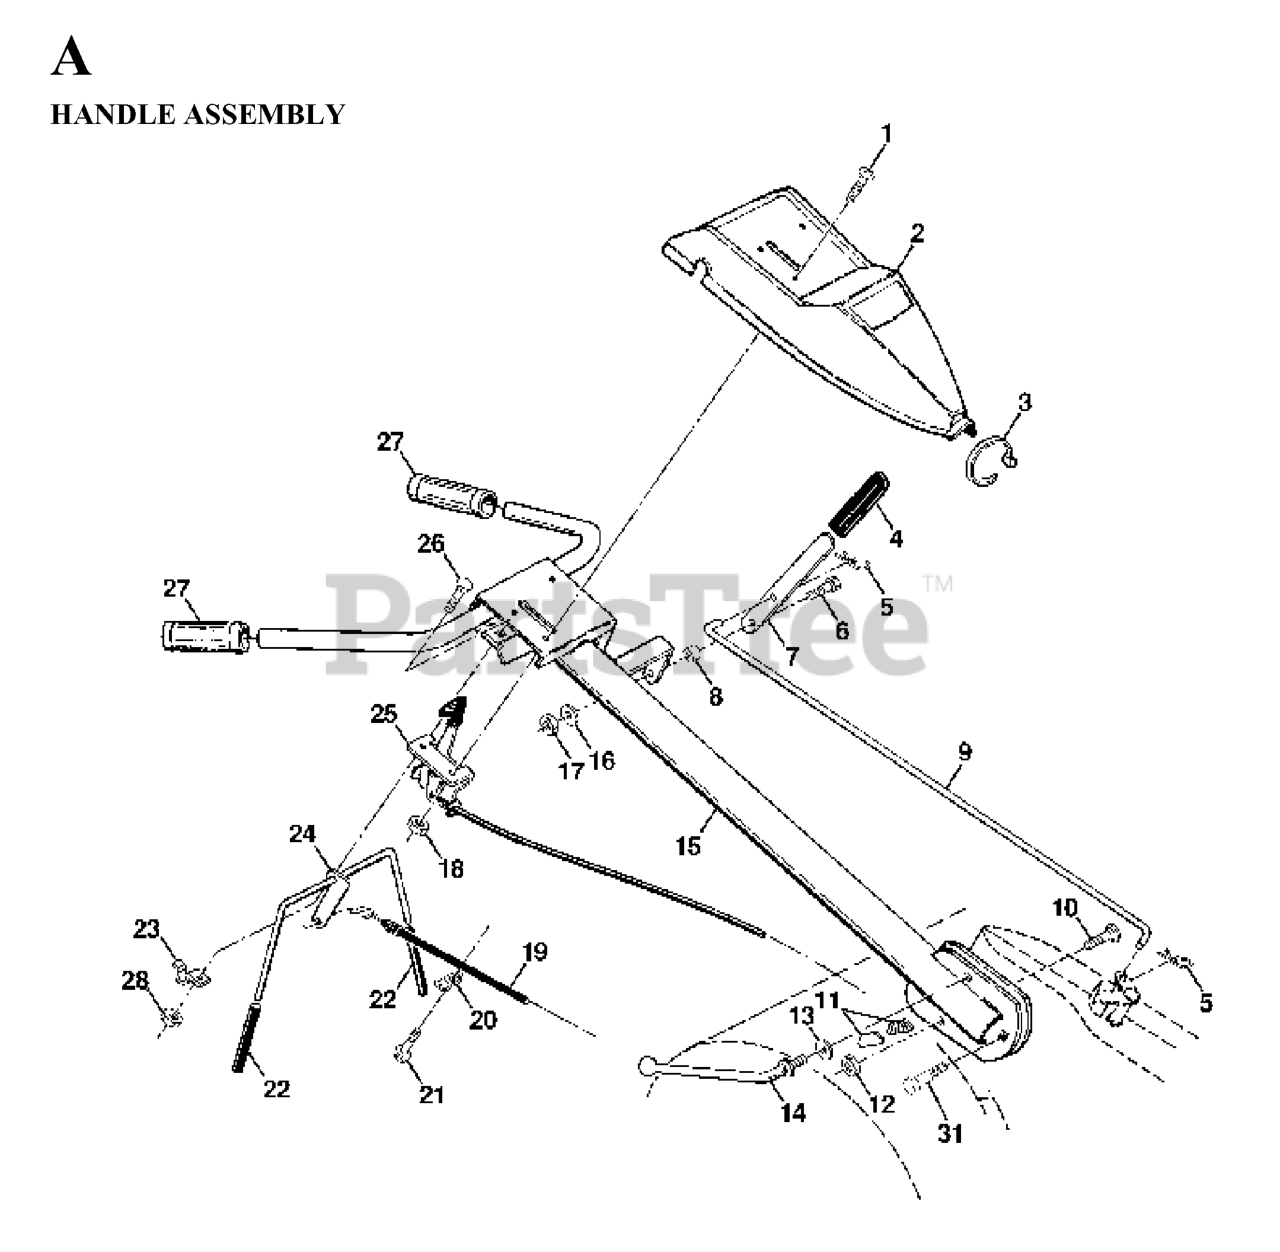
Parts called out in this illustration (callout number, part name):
1	SCREW.PNHD.10-24
3	TIE CABLE CRT
4	GRIP T
5	RETAINER M
6	SHOULDER BOLT ST
7	SHIFT HANDLE CRT
8	GROMMET.RUBBER.CRT.TILLER
9	SHIFT ROD CRT
10	BOLT D
11	LOCK.HANDLE.CRT
12	LOCKNUT
13	WASHER CRT
14	LEVER.LOCK.CRT
15	HANDLE
16	LOCKWASHER
17	NUT
18	NUT **
19	CABLE, CLUTCH 48 "Z"
20	CONDUIT.CLIP.PLATED
21	TAPPING SCREW
22	GRIP BAR CRT(1)
23	CLAMP.BAR.CRT.BLACK
24	BAR ASSY CONTROL
25	CONT,THROTTLE
27	KIT.GRIP.HANDLE.5.00.BLK.VINYL
28	NUT
31	BOLT.PIVOT
